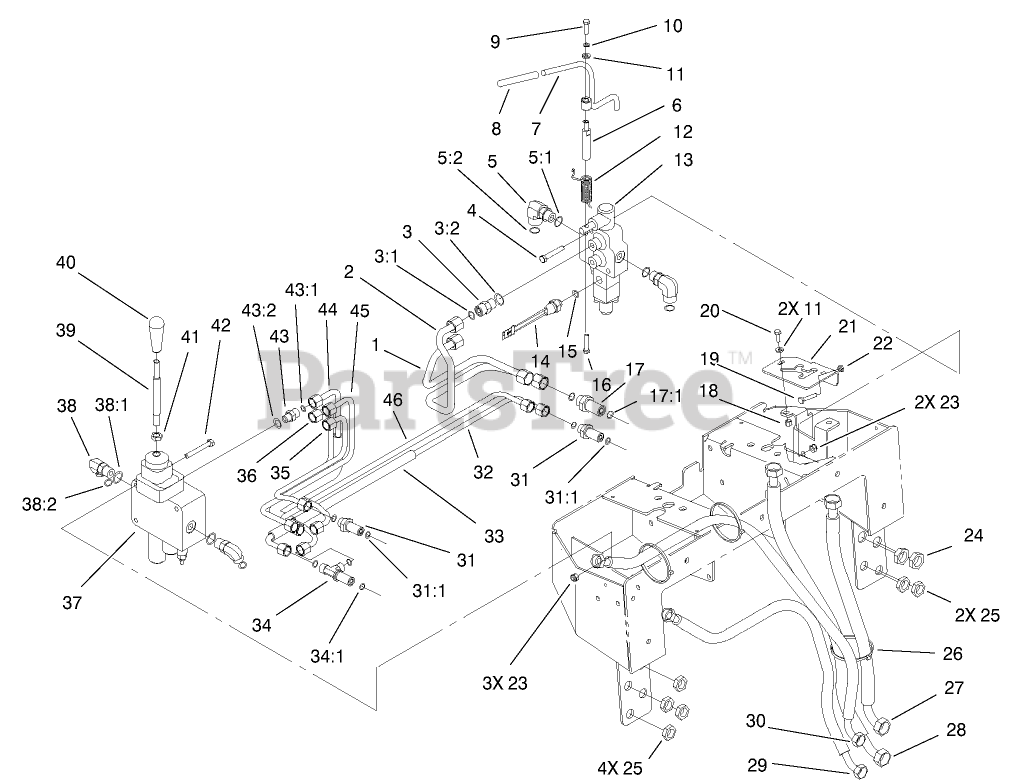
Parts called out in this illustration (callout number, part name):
1	HYD TUBE ASM
2	HYD TUBE ASM
3	FITTING-STRAIGHT
3:1	O-RING
3:2	O-RING
4	SCREW-HH
5	Fitting-Elbow, 90 DEG
5:1	O-RING
5:2	O-RING
6	SPACER-HIFLO
7	AUXILIARY LEVER ASM
8	CAP-ROD, TILT
9	SCREW-HH
10	WASHER-LOCK
11	WASHER-FLAT
12	SPRING-TORSION
13	VALVE-1 SPOOL
14	SWITCH-BALL
15	O-RING
16	SCREW
17	FITTING-BULKHEAD
17:1	O-RING
18	NUT-HEX
19	SCREW-HH
20	SCREW-HH
21	AUXILIARY STOP ASM
22	NUT-JAM
23	NUT-LOCK, NI
24	NUT-BULKHEAD
25	NUT-LOCK
26	TIE-CABLE
27	HYDRAULIC HOSE ASM
28	HYD HOSE ASM
29	HYD HOSE ASM
30	HYD HOSE ASM
31	FITTING-STRAIGHT, BULKHEAD
31:1	O-RING
32	HYD TUBE ASM
33	CONDUIT-CONVOLUTED
34	FITTING-TEE, BULKHEAD
34:1	O-RING
35	HYD TUBE ASM
36	HYD TUBE ASM
37	VALVE-2 SPOOL
38	FITTING-ELBOW-90 DEG
38:1	O-RING
38:2	O-RING
39	SHAFT-HANDLE, LIFT/TILT
40	KNOB-TAPERED
42	SCREW-HH
43	FITTING-STRAIGHT
43:1	O-RING
43:2	O-RING
44	HYD TUBE ASM
45	HYD TUBE ASM
46	HYD TUBE ASM
